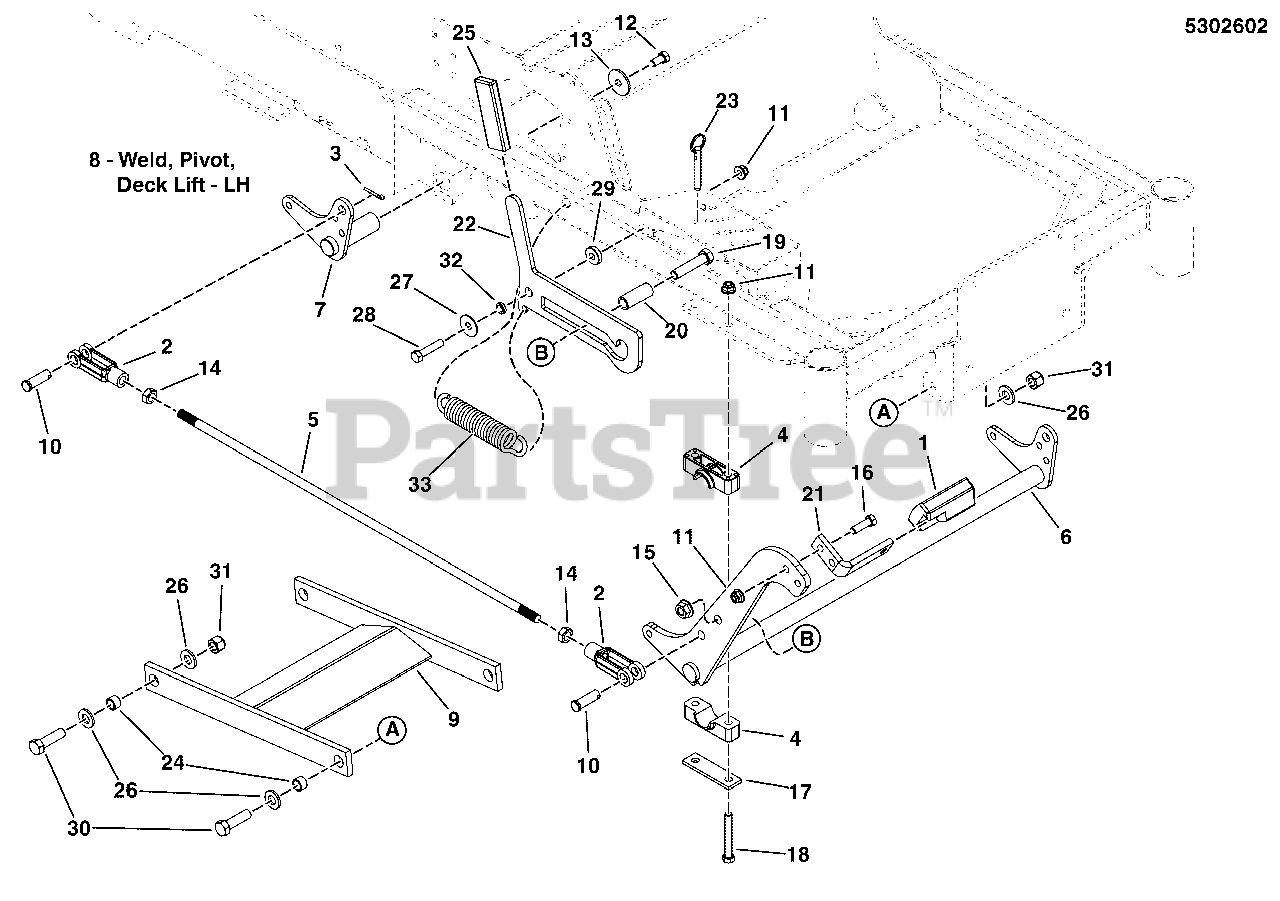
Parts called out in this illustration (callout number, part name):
1	RUBBER, FOOT PEDAL
2	CLEVIS, 1/2-20
3	PIN, HAIR, .0915 X 1-7/8
5	ROD, DECK LIFT, SNAPPER PRO
6	WELD, FRONT DECK PIVOT - RED
7	WELD, PIVOT DECK LIFT, RH - BLK
8	WELD, PIVOT, DECK LIFT, LH - BLK
9	WELD, PULLER BAR - BLK
10	PIN, CLEVIS, 1/2 X 1 1/2, YZP
11	NUT, 3/8-16, Hex Flange Nylock
12	BOLT, 3/8-16 x 3/4, GD5, YZ WITH PATCH
13	WASHER, .390 X 1.50 X .109, YZ
14	NUT, Hex Jam, 1/2-20
15	NUT, Hex Flange, 1/2-13
16	CAPSCREW, Hex Head, 3/8-16 x 1-1/4
17	PLATE, PIVOT BLOCK SUPPORT - BLK
18	CAPSCREW, Hex Head, 3/8-16 X 2-3/4
19	BOLT, 1/2-13 X 4-1/2 GD5 YZ
20	SPACER, .53 X .73 X 3.38, CZ
21	PEDAL, FOOT - BLK
22	PLATE, DECK TRANSPORT LEVER - RED
23	PIN, Hitch, 3/8 X 2 1/2
24	INSERT, BEARING
25	GRIP, FOAM, 1/4" X 1
26	WASHER, 1/2" GR. 9 FLAT
27	WASHER, Fender, 3/8
28	CAPSCREW, Hex Head, 3/8-16 X 1-3/4
29	SPACER, .39ID x 1 OD x 1/4
30	BOLT, 1/2-20 X 1-3/4" GD5 YZ
31	NUT, Hex, Nylon Lock, 1/2-20
32	SPACER, .38 X .50 X .27, CZ
33	SPRING, EXTENTION, .50 OD X 4.12 FL
